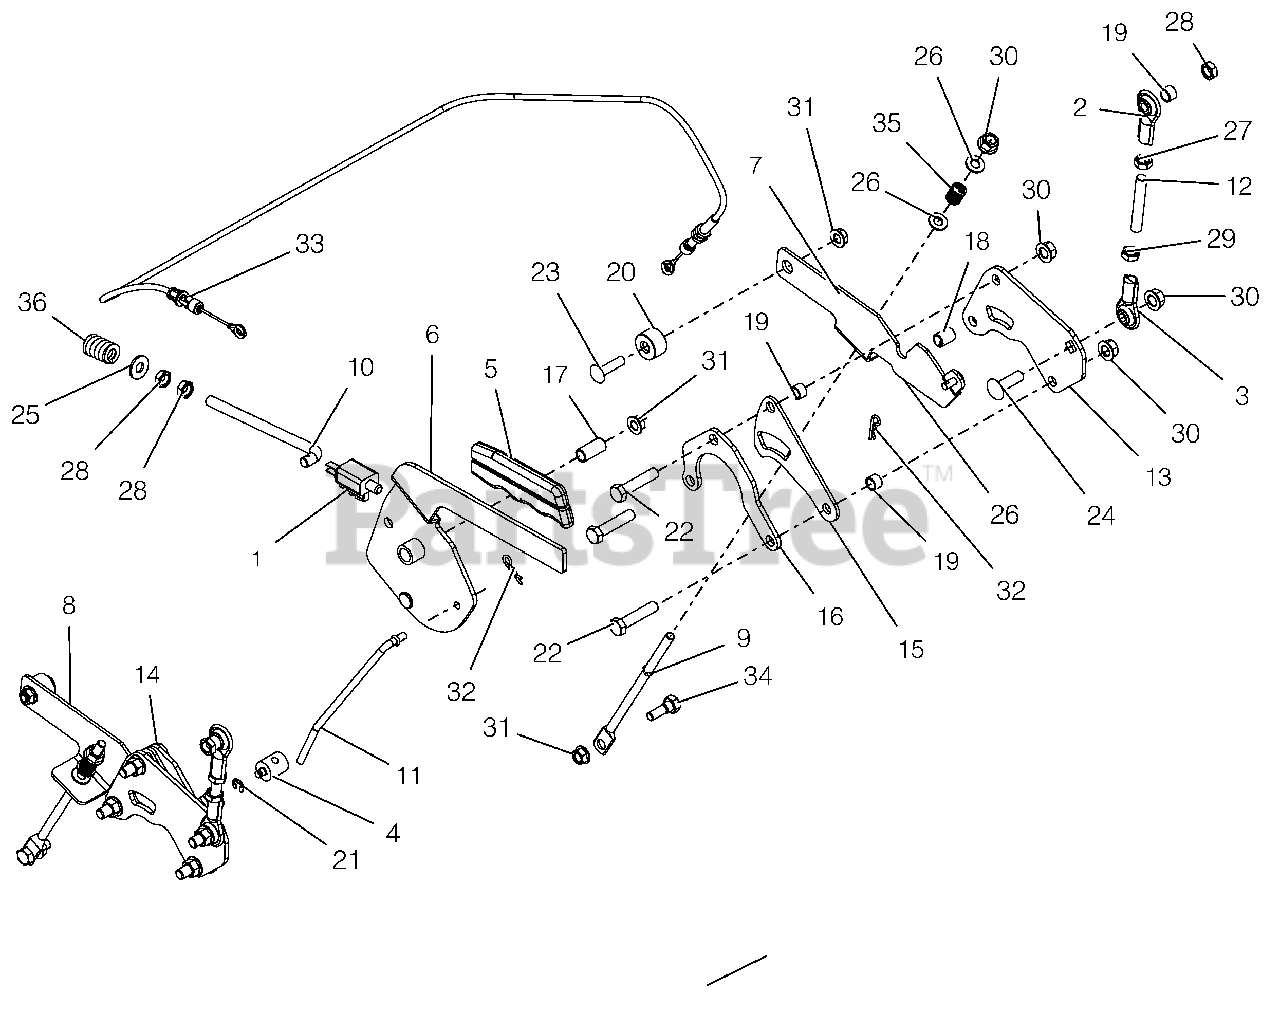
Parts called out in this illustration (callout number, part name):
1	SWITCH, SINGLE POLE N.O.
2	ROD END, .38 RH
3	END, ROD-.38 LH
4	TRUNION, 1/4-20
5	GRIP, PARKING BRAKE (YELLOW)
6	LEVER, PARKING BRAKE
7	ARM, BRAKE - LH (W/PIN)
8	ARM, BRAKE-RH
9	ROD, LINK - TRANSMISSION BRAKE
10	ROD, OVER CENTER
11	ROD, BRAKE LINK
12	ROD, STEERING LINK
13	BRKT, TRANSAXLE STEERING
14	BRKT, SPACER
15	BRKT-SPACER
16	PLATE, REAR REINFORCING
17	BSHG-SLV .385X.500X1.045
18	SPCR, SLV .385X.500X.652
19	SPCR, SLV .385X.500X.350
20	SPCR, FLANGE
21	RG-RTNG-EXT .250X.025
22	@BLT-HEX .38-16X1.75 GR5 YWZC
23	BLT-RHDSHSQNK.31-18X1.25 G5YZ
24	@BLT-RHDSSQNK .38-16X1.25 G5YZ
25	@WSHR-FL-STL.38X.875X.083 YWZC
26	@WSHR-FL-STL.344X.688X.065YWZC
27	NUT-JAM .375-24 YWZC
28	NUT-HEX-JAM .375-16 YWZC
29	NUT-JAM .375-24 LH YWZC
30	@NUT-LK-TOP-FLG .38-16 YWZC
31	@NUT-LK-TOP-FLG .31-18 YWZC
32	PIN-HAIR INT .08X.18X1.18 YWZC
33	CABLE, BRAKE
34	BOLT,SHLDR .38X.25 -.31-18X.75
35	SPRING, COMPRESSION
36	SG-COMP .187X.56X1.62
